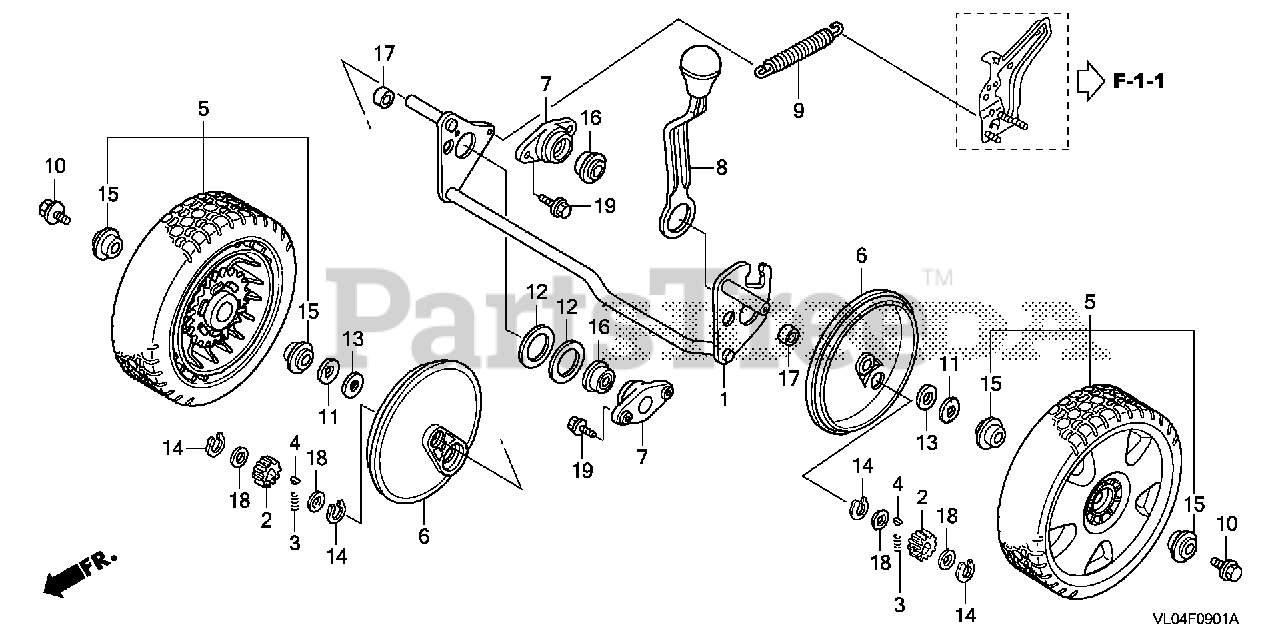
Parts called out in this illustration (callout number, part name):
1	SHAFT, RR. AXLE
2	GEAR, PINION (13T)
3	SPRING, RATCHET RETURN
4	KEY, RATCHET
5	WHEEL, RR. *NH164* (GRIP GRAY)
7	HOLDER, RR. AXLE
8	LEVER, RR. ADJUSTER *NH164* (GRIP GRAY)
9	SPRING, RR. BALANCER
10	BOLT, WHEEL
11	WASHER, WHEEL
12	WASHER (53MM)
13	WASHER, THRUST (13X27X1)
14	CIRCLIP (OUTER) (12.7MM)
15	BEARING, RADIAL BALL
15	BEARING, WHEEL
16	BEARING, WHEEL
17	COLLAR, THRUST
18	COLLAR, PINION GEAR
19	BOLT, FLANGE (6X14)
